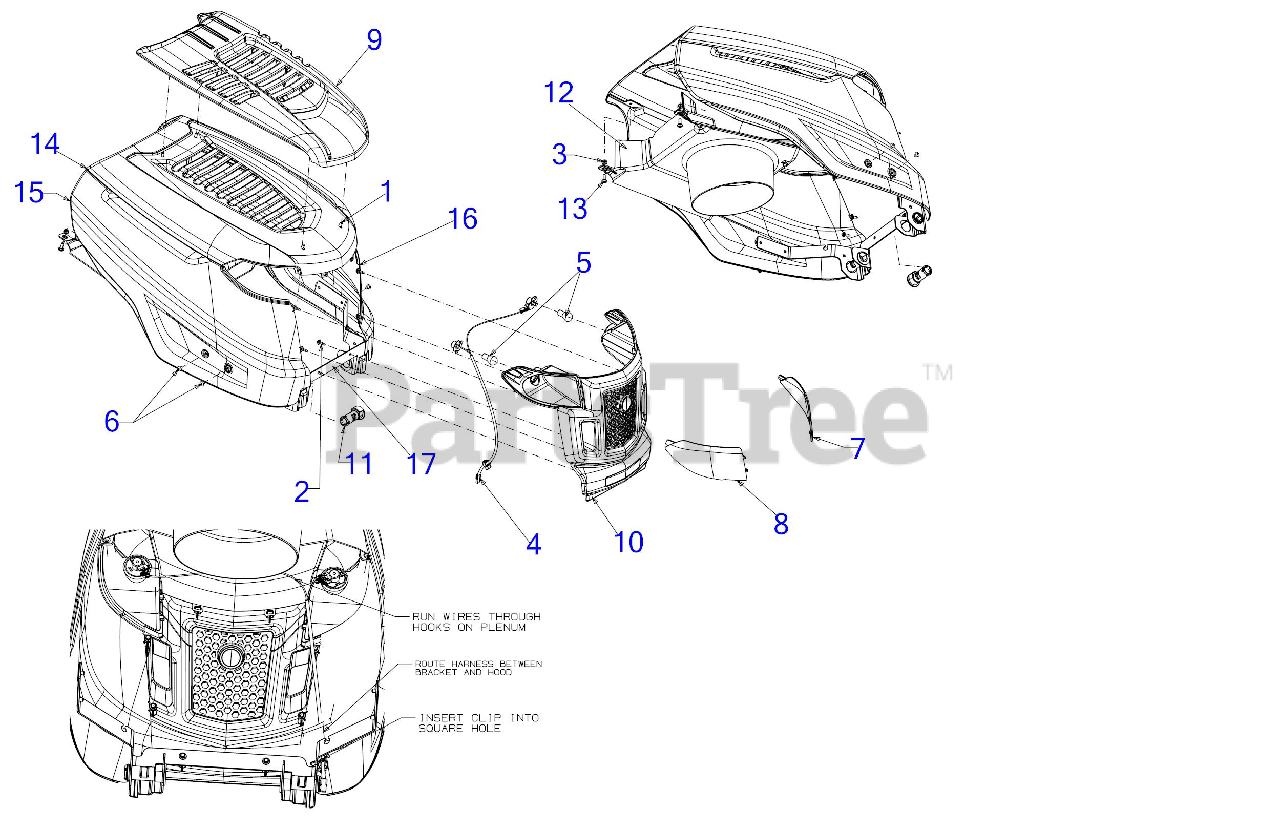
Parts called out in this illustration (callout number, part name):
1	HEX SCREW 1/4-15 x .50
2	SCREW 1/4-10 x .750
3	FLANGE LOCK NUT
4	HEADLIGHT HARNESS
5	MINIATUURE BULB 12V
6	POP RIVET 6.4MM x 10MM
7	LENS (LH)
8	LENS (RH)
9	HOOD SCOOP
10	GRILLE (K STYLE)
11	HOOD PIVOT PIN
12	PLENUM
13	SCREW 1/4-20 x .75 TORX
